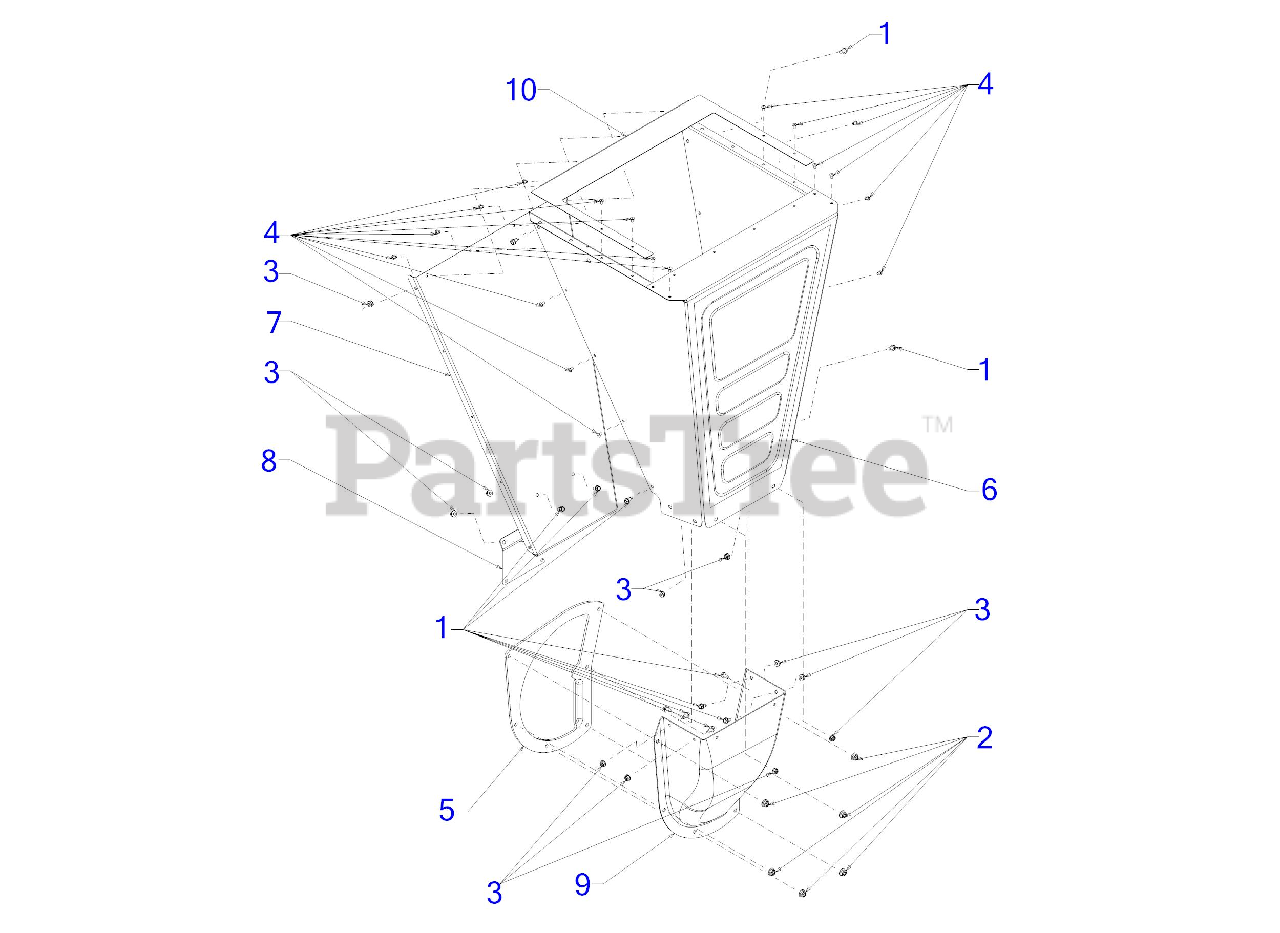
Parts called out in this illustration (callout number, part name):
1	SCREW 1/4-20 X.500
2	HEX FLANGE NUT
3	FLANGE LOCK NUT
4	FULL TUBULAR RIVET
5	SHREDDER PLATE
6	HOPPER FRONT PANEL
7	HOPPER BACK PANEL
8	HOPPER BRACKET SUPPORT
10	HOPPER TOP PANEL
